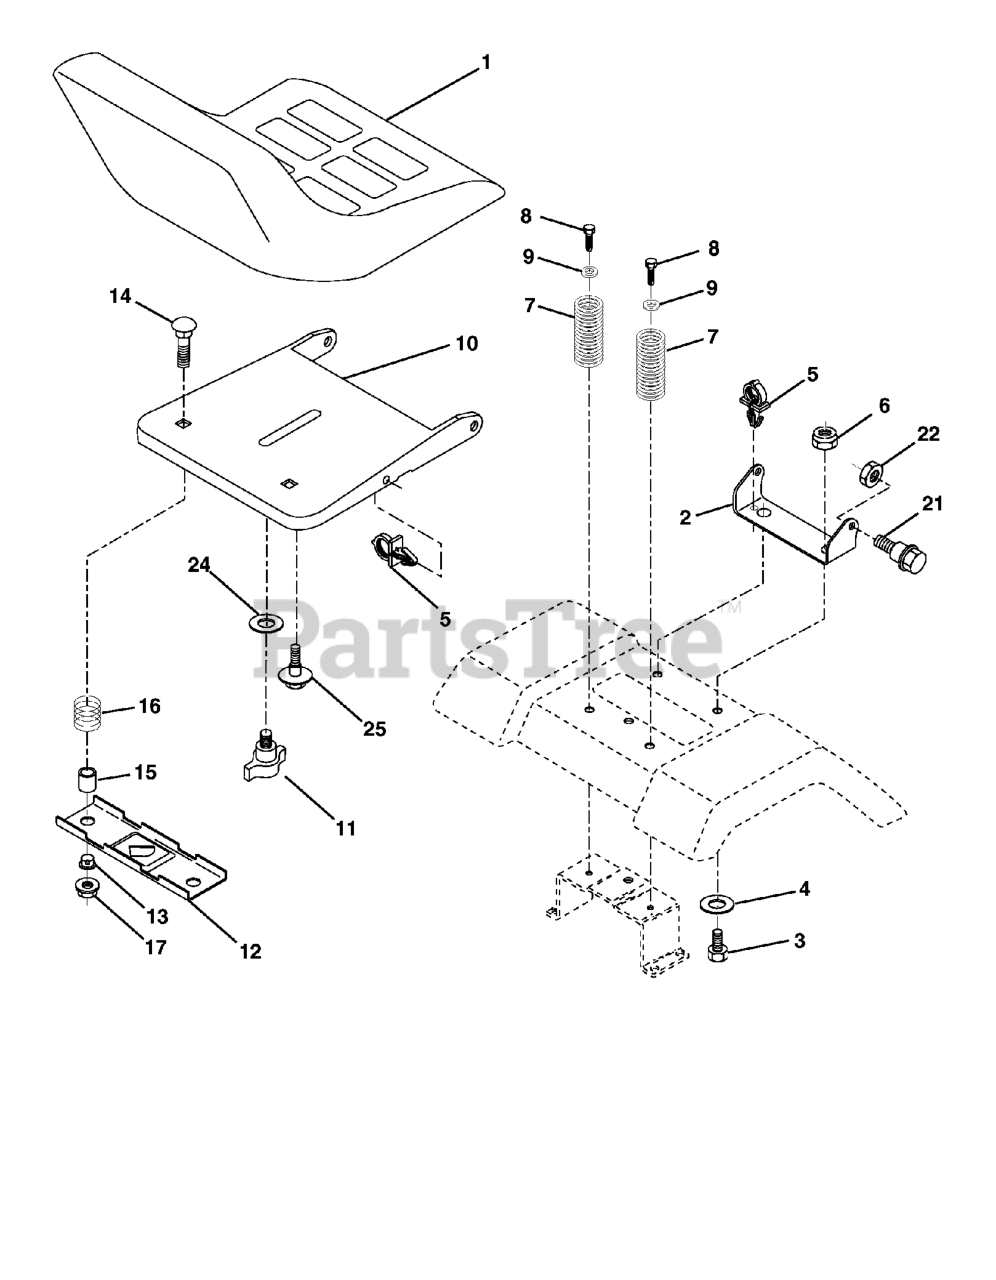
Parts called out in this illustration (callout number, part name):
1	SEAT.XH150.GRY
2	SEAT PIVOT BRKT
3	BOLT, HEX 3/8-16X1
4	WASHER PM
5	PUSH CLIP
6	NUT
7	SPRING COMPRESSION
8	SCREW 3/8-16X1
9	WASHER
10	PAN SEAT
11	KNOB.SEAT.ADJ.WINGNUT
12	BRKT.MNTNG.SWITCH.SEAT.BLACK
13	BUSHING
14	BOLT.ROUND.HEAD.SQUARE.NECK
15	WASHER
16	SPRING COMPRESSED
17	NUT T
21	BOLT.SHOULDER.5/16-18
22	NUT.71038.31-18.HEX.NYLOCK
24	WASHER
25	BOLT,SHOULD
